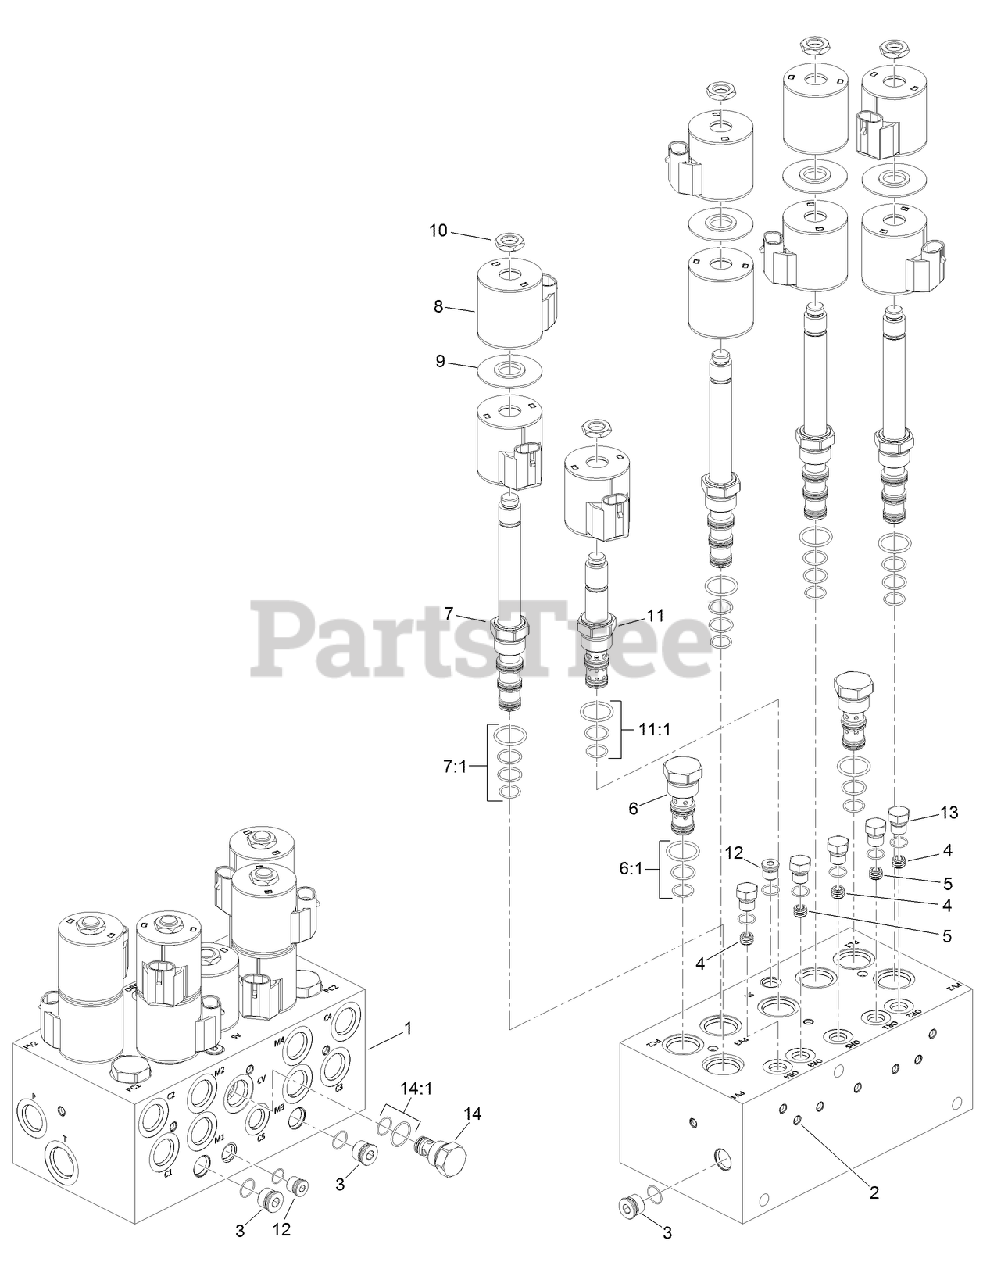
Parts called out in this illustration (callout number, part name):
1	BLOCK-MANIFOLD
2	Deck ASM
4	PLUG-ORIFICE (0.050 INCH)
5	ORIFICE
6	VALVE-CHECK
6:1	SEAL KIT
7	VALVE-SOLENOID
7:1	SPOOL VALVE SEAL KIT
8	COIL-12V, DC
9	SPACER-E COIL
10	NUT-COIL
11	VALVE-SOLENOID
11:1	SEAL KIT
14	CHECK VALVE ASM
14:1	SEAL KIT
